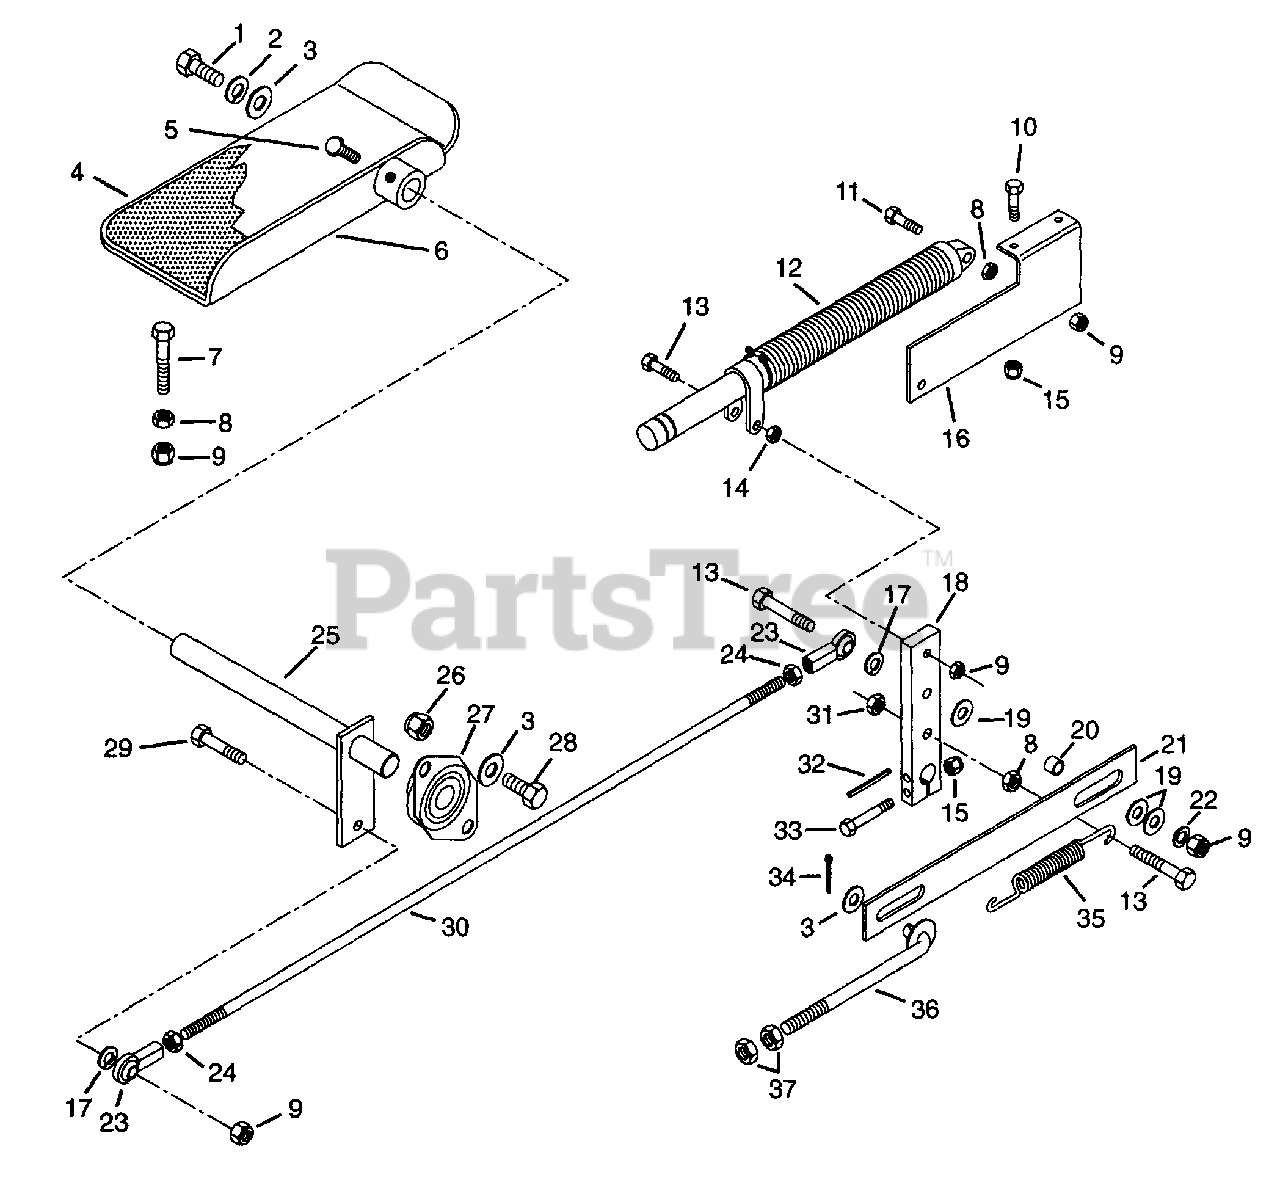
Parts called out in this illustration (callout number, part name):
1	Bolt-Hex .38-16 x 1.00 Grade 5
2	Washer-Lock .38 x .094
3	Washer-Flat-Steel .406 x .812 x .065
4	Cover, Large Footboard
5	Bolt-Hex .25-28 x .50
6	Weldment, Foot Control Lever
7	Bolt-Hex .31-18 x 2.50 Grade 5
8	Nut-Hex .31-18
9	Nut-Locking-Nylon .312-18 Grade 2
10	Bolt-Hex .25-20 x .50 Grade 5
11	Bolt-Hex .31-18 x 1.75 Grade 5
12	Damper
13	Bolt-Hex .31-18 x 2.00 Grade 5
14	Nut-Jam .312-18
15	Nut-Locking-Center .25-20
16	Bracket, Damper
17	Washer-Locking .31 x .078
18	Arm, Pump
19	Washer-Flat-Steel .531 x 1.06 x .095
20	Bushing, Steel .328 x .500 x .500
21	Strap, Neutral Detent
22	Washer-Flat-Steel .344 x .688 x .065
23	Rod End, 5/16" Female
24	Nut-Jam .375-24
25	Weldment, Control
26	Nut-Locking-Center .38-16
27	Bearing-Flange .75 x 2 Holes x 2.123
28	Bolt-Hex .38-16 x .75 Grade 5
29	Bolt-Hex .31-18 x 1.25 Grade 5
30	Rod, Speed Control
31	Nut-Locking-Center .31-18
32	Pin-Roll .250 x 1.000
33	Bolt-Hex .25-20 x 1.75 Grade 5
34	Pin-Center .09 x 1.00
35	Spring-Tension .091 x .500 x 5.50
36	Weldment, Detent Rod
37	Nut .312-24
